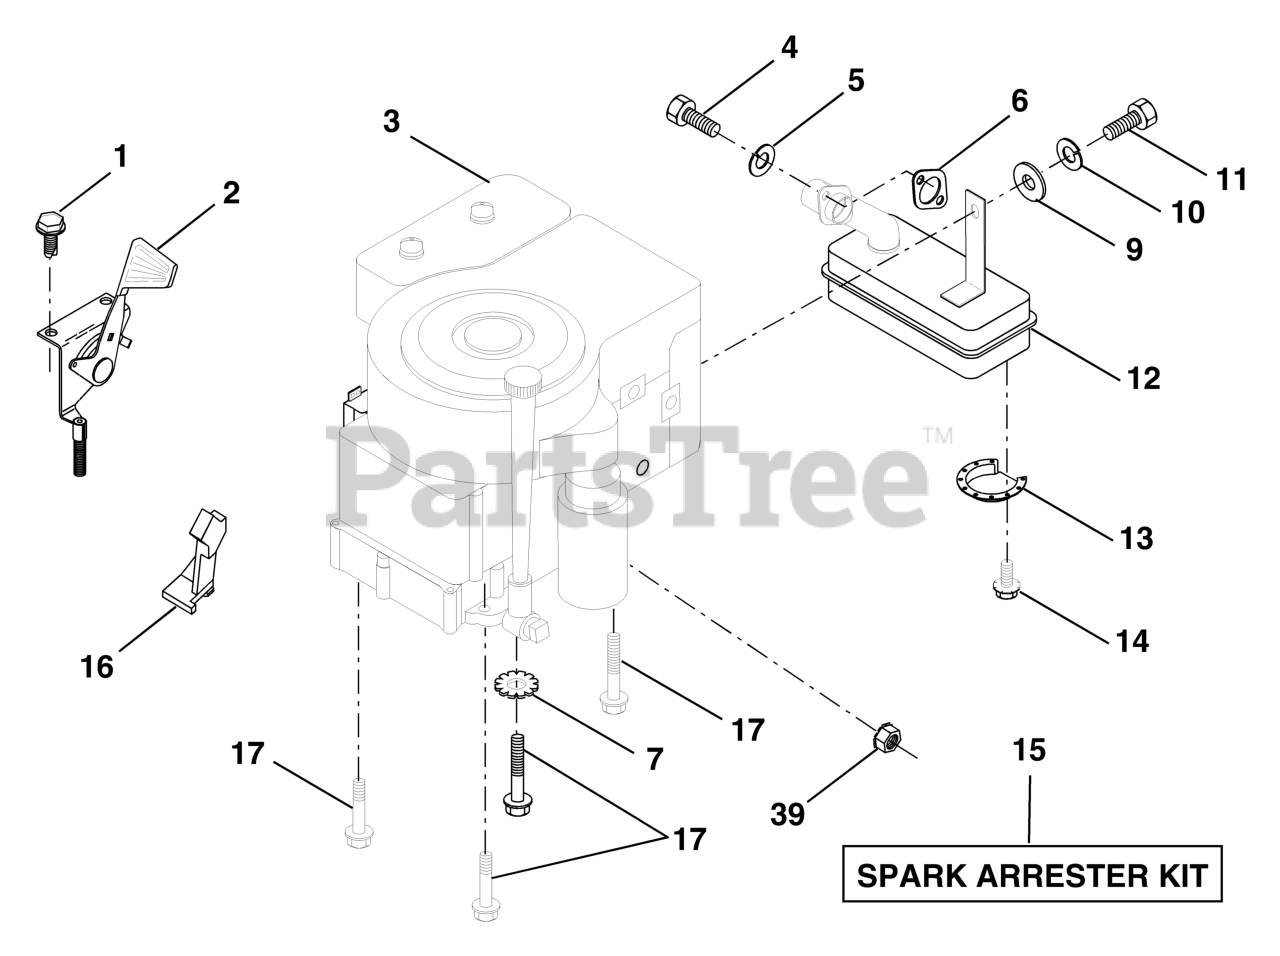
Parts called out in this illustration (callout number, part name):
2	CONTROL.TH/CH.RH.BLK.FLG.EEC
4	SCREW
5	WASHER.LOCK.HVY.HLCL.SPR.5/16
6	GASKET.ENG.1.313 ID.TIN PLATED
7	LOCKWASHER
9	WASHER
10	LOCKWASHER
11	Bolt, Hex Fin.
12	MUFFLER.SINGLE.B&S.12HP
13	DEFL MUFFLER LTV
14	SCREW
15	KIT.SPARK ARRESTOR 794945 B&S
16	STOP THROTTLE
17	SCREW LT
39	NUT FLANGE 1/4-20 STARTER NUT
